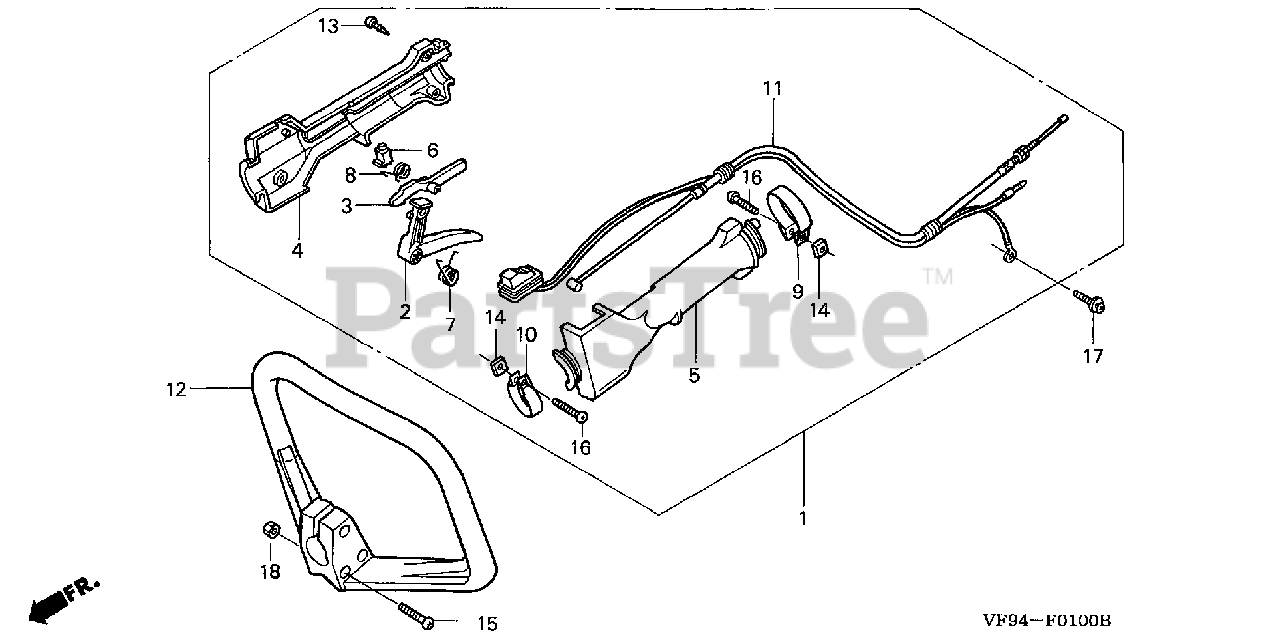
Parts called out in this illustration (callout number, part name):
1	LEVER ASSY., THROTTLE
2	LEVER, THROTTLE
3	LEVER, THROTTLE LOCK
4	GRIP, R. THROTTLE LEVER
5	GRIP, L. THROTTLE LEVER
6	BUTTON, THROTTLE LOCK
7	SPRING, THROTTLE LEVER
8	SPRING, THROTTLE LOCK LEVER
9	BRACKET, THROTTLE LEVER
10	BRACKET, THROTTLE LEVER
11	WIRE HARNESS ASSY.
12	HANDLE, LOOP
13	SCREW, TAPPING (4X18)
14	NUT, SQUARE (6MM)
15	SCREW, PAN (5X28)
16	SCREW, PAN (6X20)
17	SCREW-WASHER (5X12)
18	NUT, HEX. (5MM)
